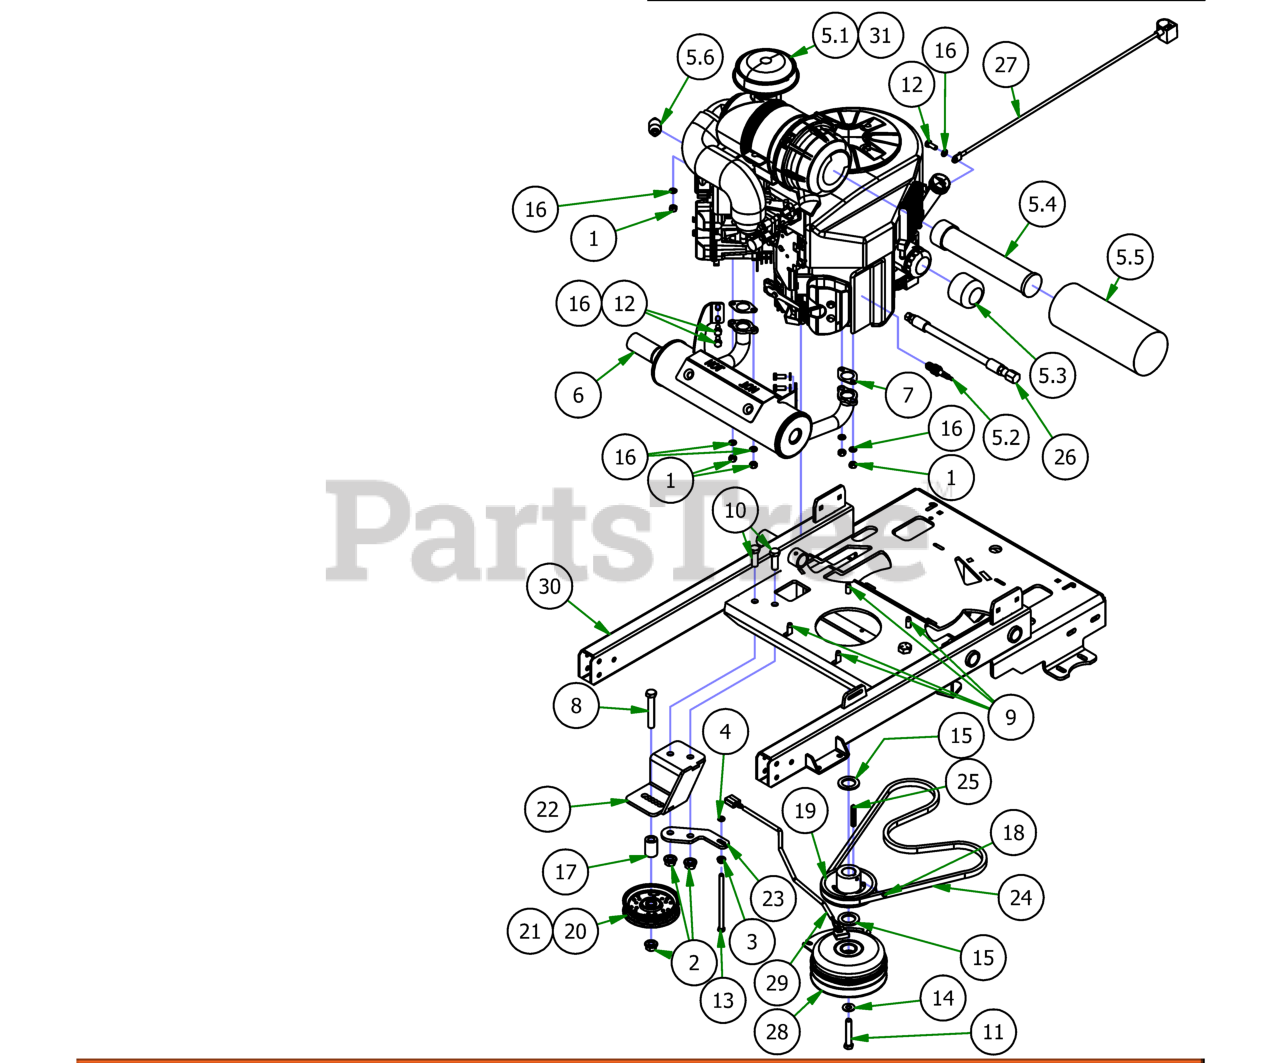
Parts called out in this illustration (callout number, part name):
1	M8-1.25 DIN 934 HEX NUT (CL.8) ZINC
2	1/2-13 NYLON INSERT FLANGE LOCKNUT ZINC
3	5/16-18 HEX SERRATED FLANGE NUT HARD/ZINC
4	5/16-18 NYLON INSERT JAM LOCKNUT ZINC
5	Kawasaki FX850 Engine
5.1	Kawasaki Engine FX-850-V-CS09R
5.2	Spark Plug - Kawasaki
5.3	Oil Filter
5.4	Canister Air Filter- Inner
5.5	Canister Air Filter- Outer
5.6	Universal Inline Fuel Filter
6	Revolt Kawasaki FX850 Exhaust
7	Exhaust Gasket
8	1/2-13 X 3-1/4 HEX CAP SCREW (GR.5) ZINC
9	3/8-16 X 1-1/8HEX WASHER UNSLOT SERRATED (TRI-LOB) TRS
10	1/2-13 X 1-1/2 HEX CAP SCREW (GR.5) ZINC
11	7/16-20 X 2-1/2 HEX CAP SCREW (GR.8) ZINC YELLOW
12	M8-1.25 X 20MM DIN 933 HEX TAP BOLT (CL 8.8) ZINC
13	5/16-18 X 5-1/2 HEX CAP SCREW (GR.5) ZINC
14	3/8 FLAT WASHER USS (1" OD) ZINC
15	1.140 ID X 1.750 OD X .132 THICK FLAT WASHER PLAIN
16	5/16 SPLIT LOCKWASHER ZINC
17	.502 ID X .750 OD X 1.500 Long Spacer
18	5/16-24 X 1/4 SOCKET SET SCREW (CUP PT) PLAIN
19	4 3/4 Motor Pulley
20	4 3/4 Idler Pulley - ABFI-76 (54" Deck Only)
21	5 3/4 Idler Pulley-Don Dye (61" Deck Only)
22	Idler Pulley Bracket Weldment
23	2019 Stand On Clutch Stop Bracket
24	2019 Stand On Pump Belt (Timken# 47-2827)
25	1/4 X 2 SQ MACHINERY KEY 1018 STL PLAIN
26	Kawasaki Oil Drain
27	24 inch Black Cable – MZ/ZT
28	Clutch Assembly
29	Clutch Pigtail
30	2019 Stand On Frame Weldment
31	Kawasaki Harness Adapter
